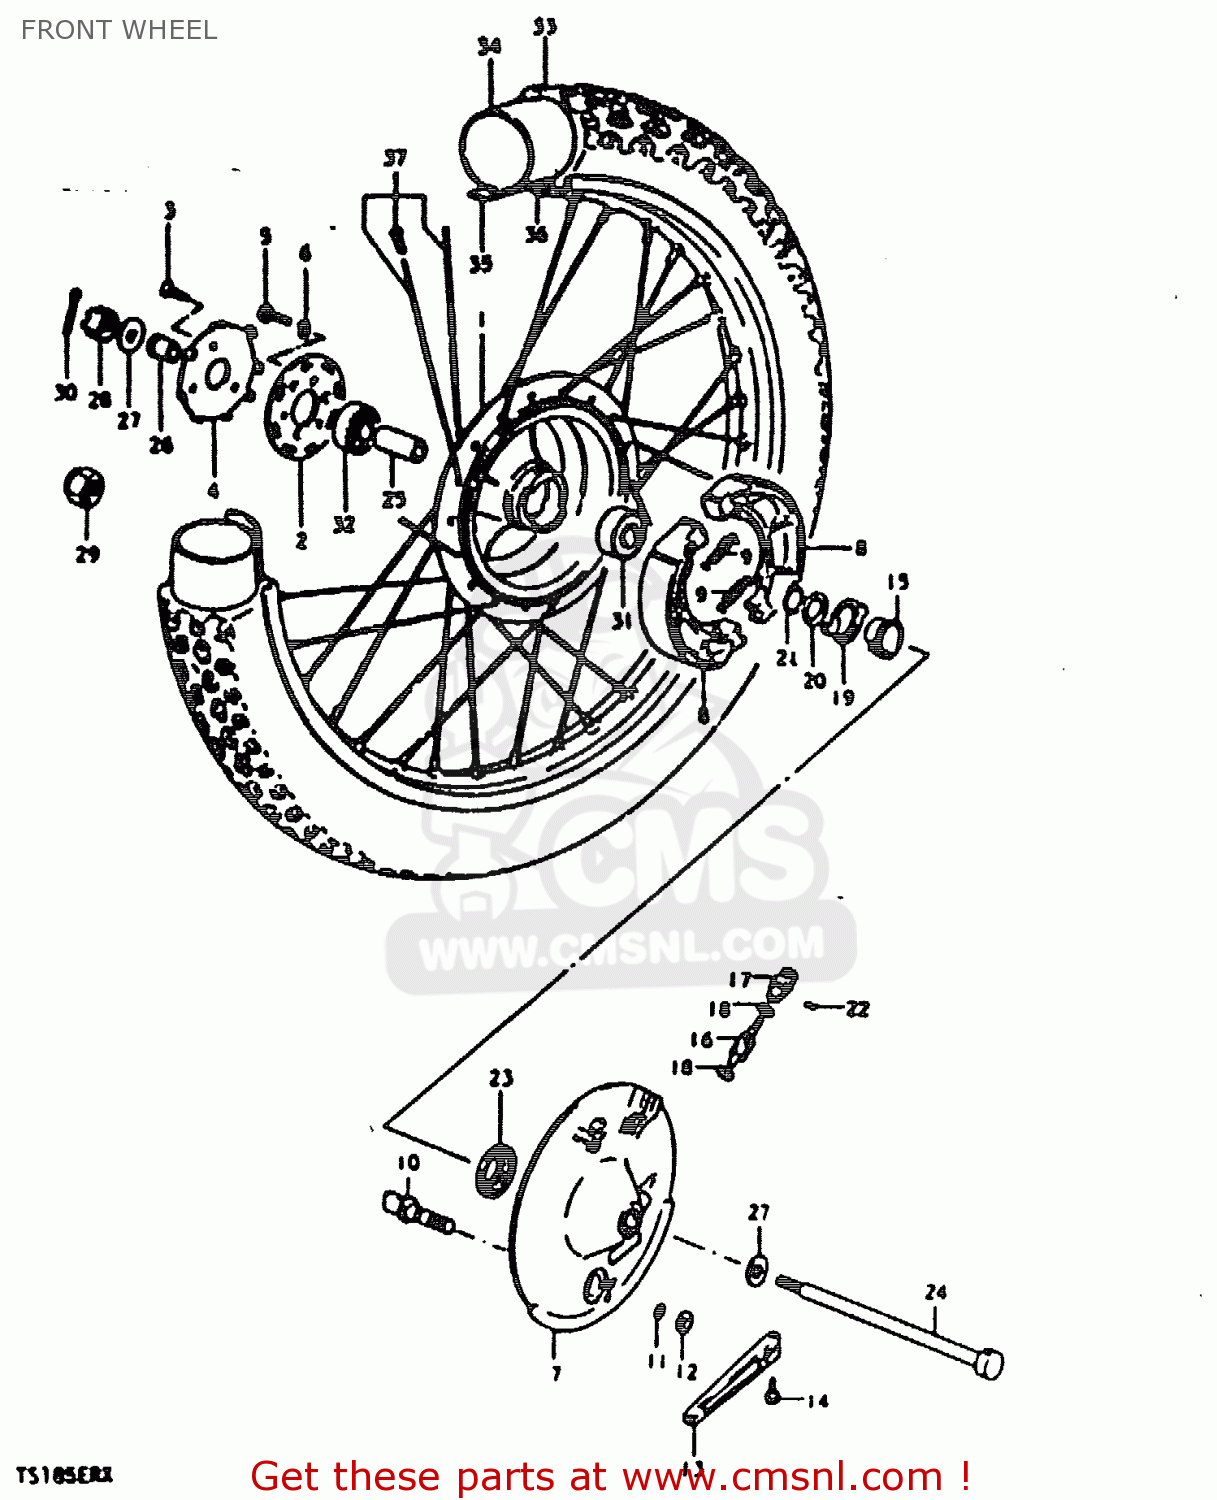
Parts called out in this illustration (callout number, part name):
1	HUB,FR WHEEL
2	FLANGE,FR HUB,R
3	SCREW
4	RETAINER,FR HUB BEARING,R
5	BOLT, UPPER
6	LOCK WASHER
7	PANEL,FRONT HUB
8	SHOE,BRAKE
9	SPRING(L:34)
10	CAM, BRAKE
11	O-RING (D:2.4 ID:13.8)
12	WASHER (14.5X22X1.6)
13	LEVER,FRONT BRAKE CAM
14	BOLT
15	GEAR,SPEEDOMETER
16	PINION,SPEEDOMETER
17	BUSH,METER GEAR OUTER
18	WASHER (5.1X9X0.4)
19	DRIVER,SPEEDOMETER GEAR
20	WASHER(18.5X24X1)
21	CIRCLIP
22	SCREW
23	OIL SEAL (43X58X7)
24	AXLE,FRONT
25	SPACER (12.6X19X52)
26	SPACER,FR AXLE,R
27	WASHER
28	NUT
30	COTTER PIN
31	BEARING
32	BEARING, RH
33	TIRE,FR
34	TUBE
35	PROTECTOR,WHEEL,INNER
36	RIM,FR WHEEL(1.60X21)
37	SPOKE SET,FR
